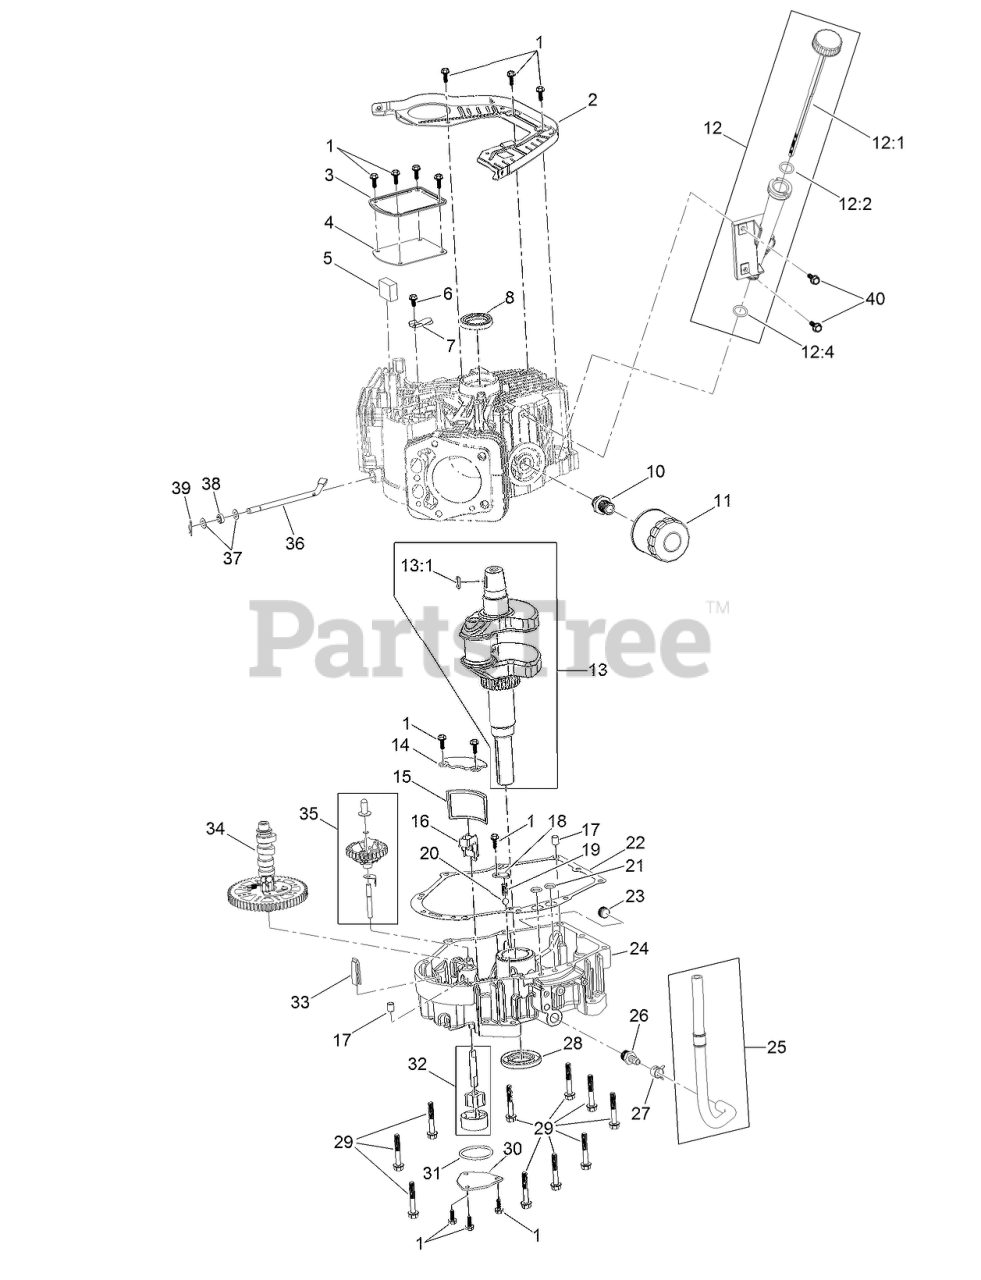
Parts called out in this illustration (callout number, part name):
1	SCREW-HHF
2	BAFFLE
3	COVER-BREATHER
4	GASKET-BREATHER
5	FILTER-BREATHER
6	SCREW-HHF
7	VALVE-BREATHER
8	SEAL-OIL
10	ADAPTOR-FILTER, OIL
12	OIL TUBE ASM
12:1	DIPSTICK
12:2	O-RING
12:4	O-RING
13	CRANKSHAFT
13:1	KEY-WOODRUFF
14	COVER-SCREEN, OIL
15	SCREEN-OIL
16	RETAINER-SCREEN
17	PIN-DOWEL
18	PLATE-RETAINER
19	SPRING
20	VALVE-BALL
21	O-RING
22	GASKET-COVER, CRANKCASE
23	PLUG-DRAIN
24	COVER-CRANKCASE
25	OIL DRAIN HOSE ASM
26	FITTING-HOSE
27	CLAMP-HOSE
29	SCREW-HHF
30	COVER-OIL PUMP
31	O-RING
32	OIL PUMP ASM
33	DEFLECTOR-OIL, RUBBER
34	CAMSHAFT
35	GOVERNOR ASM
36	SHAFT-GOVERNOR
37	WASHER-PLAIN
38	SEAL-OIL
39	PIN-HAIR
40	SCREW-HHF
